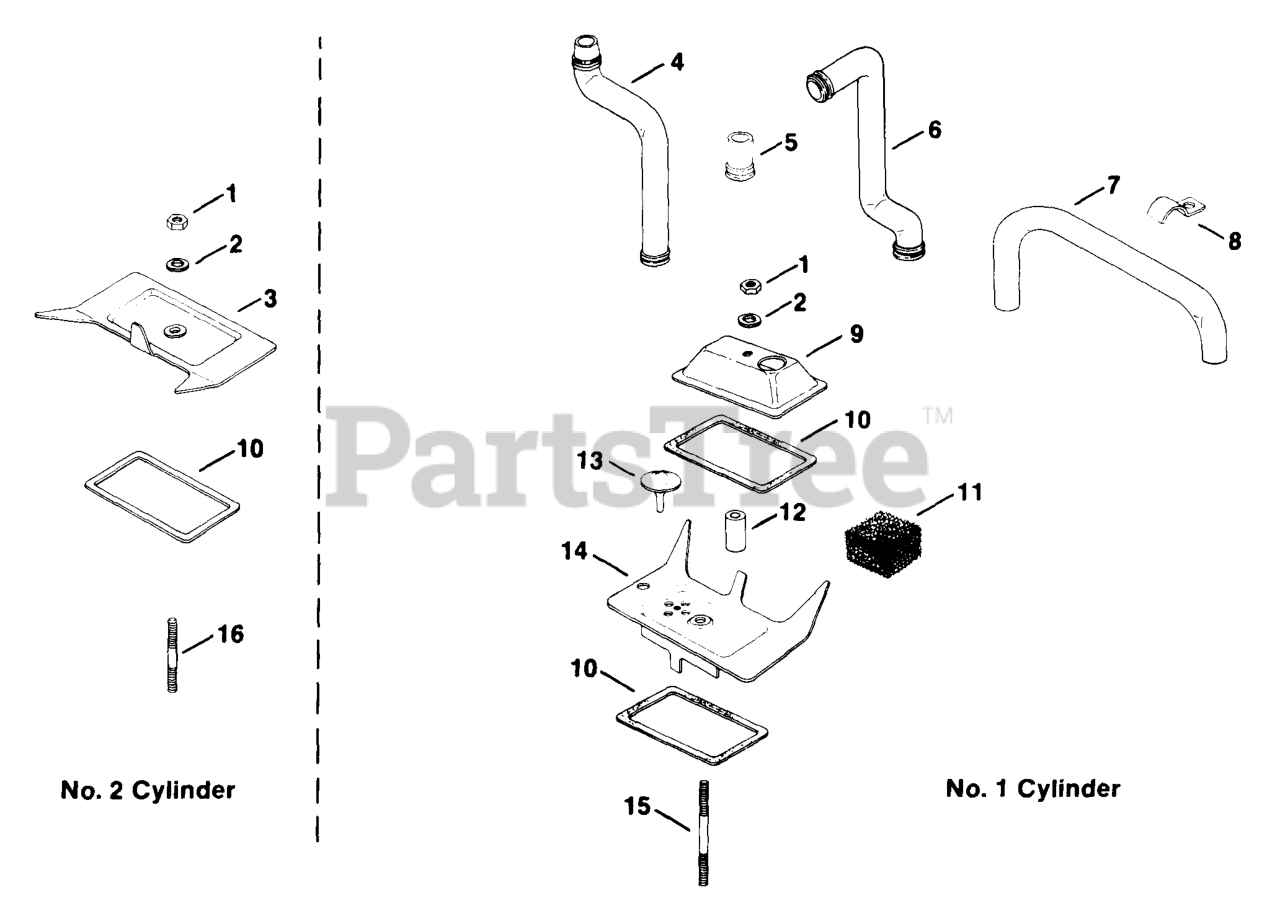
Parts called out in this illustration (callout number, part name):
1	Nut, hex. 1/4-20
2	Washer, plain 1/4"
3	COVER - USE 52 096 55
4	HOSE, BREATHER-USE 25 326 06-S
11	FILTER, BREATHER
13	VALVE, UMBRELLA - DISCONTINUED
14	BREATHER - USE 52 035 02
15	STUD, 1/4-20x3-1/4" - DISCONTINUED
16	STUD, 1/4-20x2-1/4" USE 25 072 11-S
